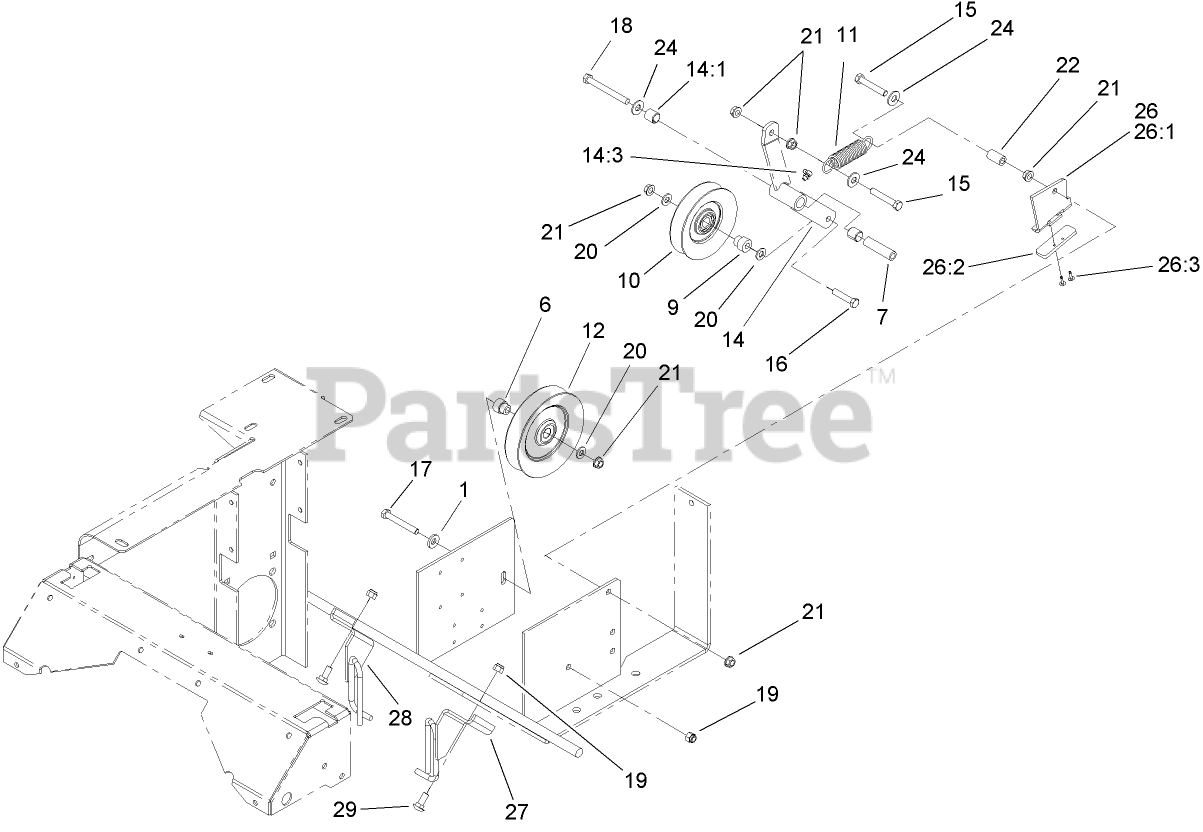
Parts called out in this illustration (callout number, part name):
1	WASHER-BELLEVILLE
6	Bushing-Idler
7	BUSHING-PIVOT, IDLER
9	BUSHING-IDLER
10	Idler
11	SPRING-EXTENSION
12	PULLEY-IDLER
14	Arm ASM
14:1	SLEEVE-BEARING
14:3	FITTING-GREASE, 90 DEG
15	SCREW-HH
16	SCREW-HH
17	SCREW-HH
18	SCREW-HH
19	NUT-LOCK, NI
20	WASHER-FLAT
21	NUT-HHF, WHIZ
22	SPACER
24	WASHER-FLAT
26	Travel Limiter ASM
26:1	Plate-Limiter, Pulley
26:2	PAD-BUMPER
26:3	RIVET
27	GUIDE-BELT, LH
28	GUIDE-BELT, RH
29	BOLT-CARR
